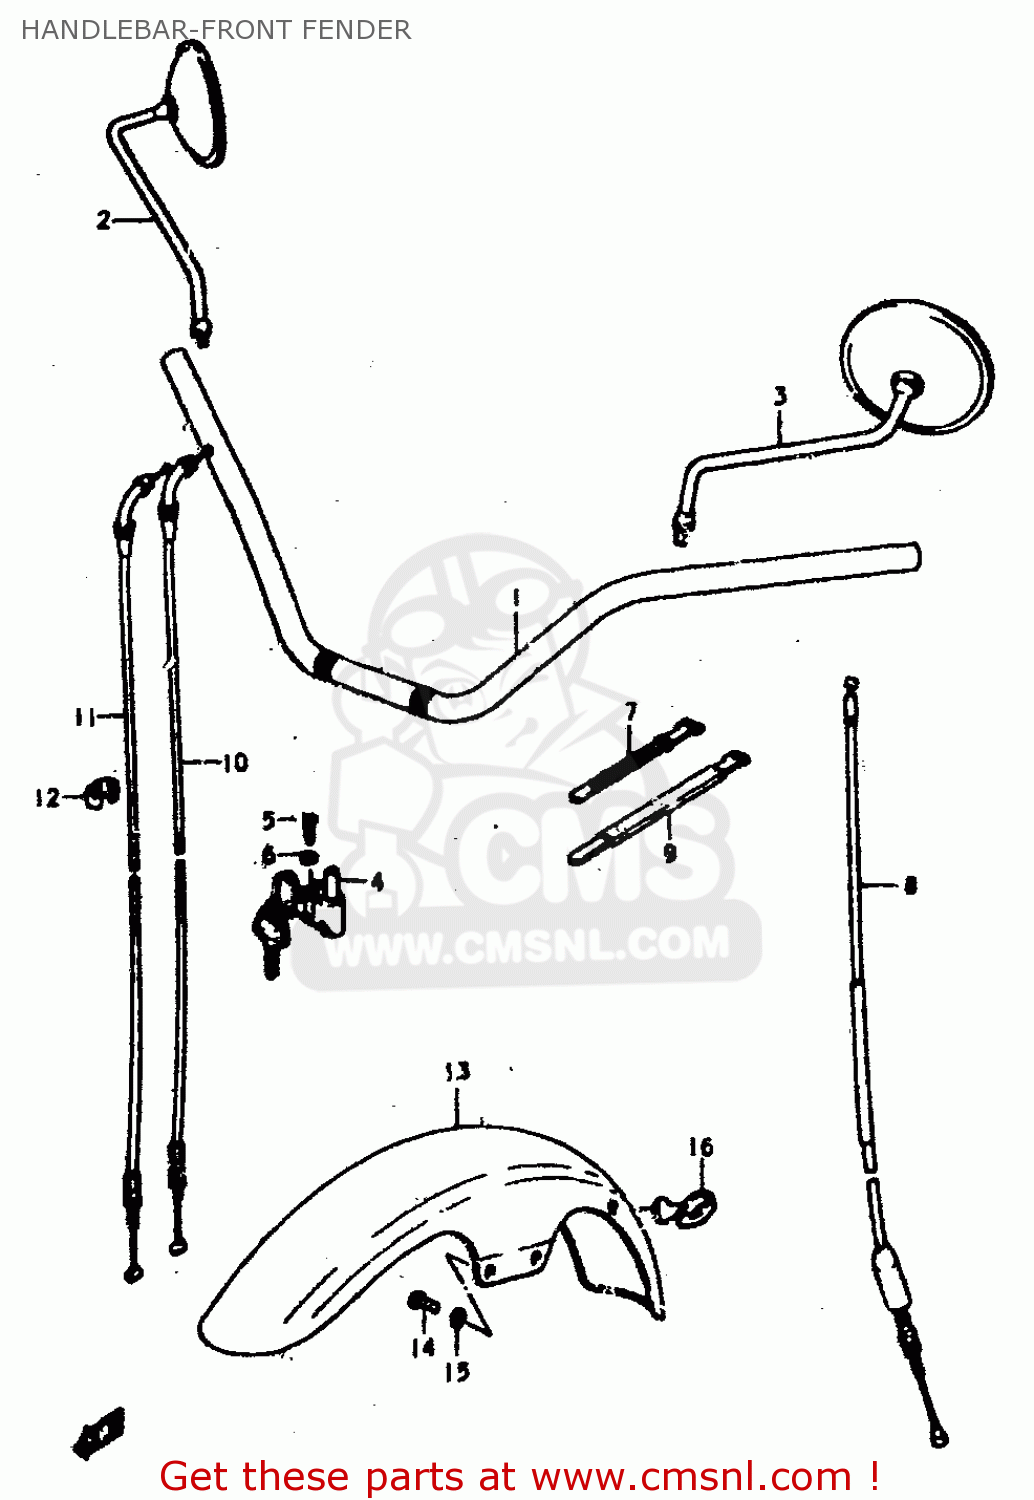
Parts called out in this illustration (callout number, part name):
1	HANDLEBAR
2	MIRROR ASSEMBLY,RIGHT
3	MIRROR ASSEMBLY,LEFT
4	LOCK ASSEMBLY,STEERING
5	SCREW
6	LOCK WASHER
7	CLAMP(L:120)
8	CABLE ASSEMBLY,CLUTCH
9	CLAMP
10	CABLE ASSEMBLY,THROTTLE
11	CABLE ASSEMBLY,THROTTLE
12	CLIP
13	FENDER,FRONT
14	BOLT
15	LOCK WASHER
16	GUIDE,CABLE
